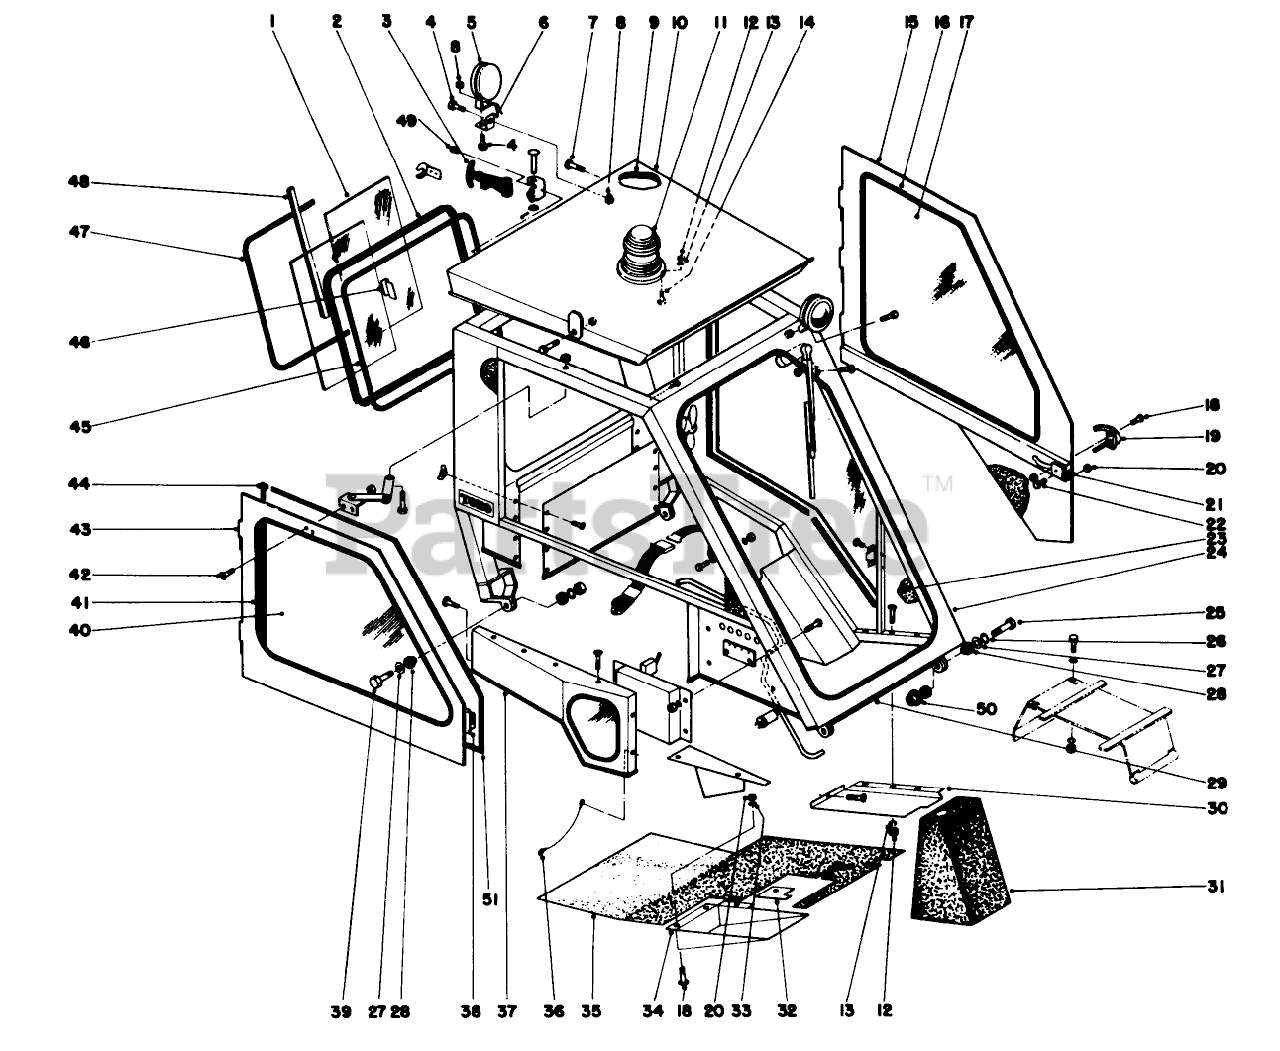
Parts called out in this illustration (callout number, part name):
1	Back Glass
2	Back Combination Channel
3	Switch
4	SCREW-HH
5	Rear Working Light
6	Tail Light Bracket
7	SCREW-HWH
8	NUT-HEX, SIDE DEFORM
9	1" Insulation
10	Roof Assembly
11	Flashing Amber Beacon
12	NUT-HEX
13	WASHER-LOCK
14	SCREW-SRH
15	Left Door
16	Left Door Window Rubber
17	Left Door Window Glass
19	Door Handle-Locking
20	NUT-HEX, SIDE DEFORM
21	Inside Door Handle-L.H.
22	SCREW-HH
23	Left Front Filler-Polyfoam
24	Cab Frame
25	Capscrew
26	WASHER-LOCK
27	WASHER-FLAT
28	Rubber Mount
29	Back Sealing Rubber
30	Left Front Corner
31	Fabric Boot Around Steering
32	Left Pocket Holder
33	WASHER-FLAT
34	Fabric Boot For Foot Pedal
35	Floor Mat
36	Ground Wire
37	Back Sealing Rubber
38	Inside Window Handle-R.H.
39	SCREW-HH
40	Right Door Window Glass
41	Left Door Window Rubber
42	SCREW
43	Right Door
44	DOOR WEATHER STRIP
45	Back Combination Rubber
46	WINDOW HANDLE
47	Spacing Rubber
48	Window Sealing Felt
49	SCREW-HWH
50	Front Mount
51	DOOR WEATHER STRIP
